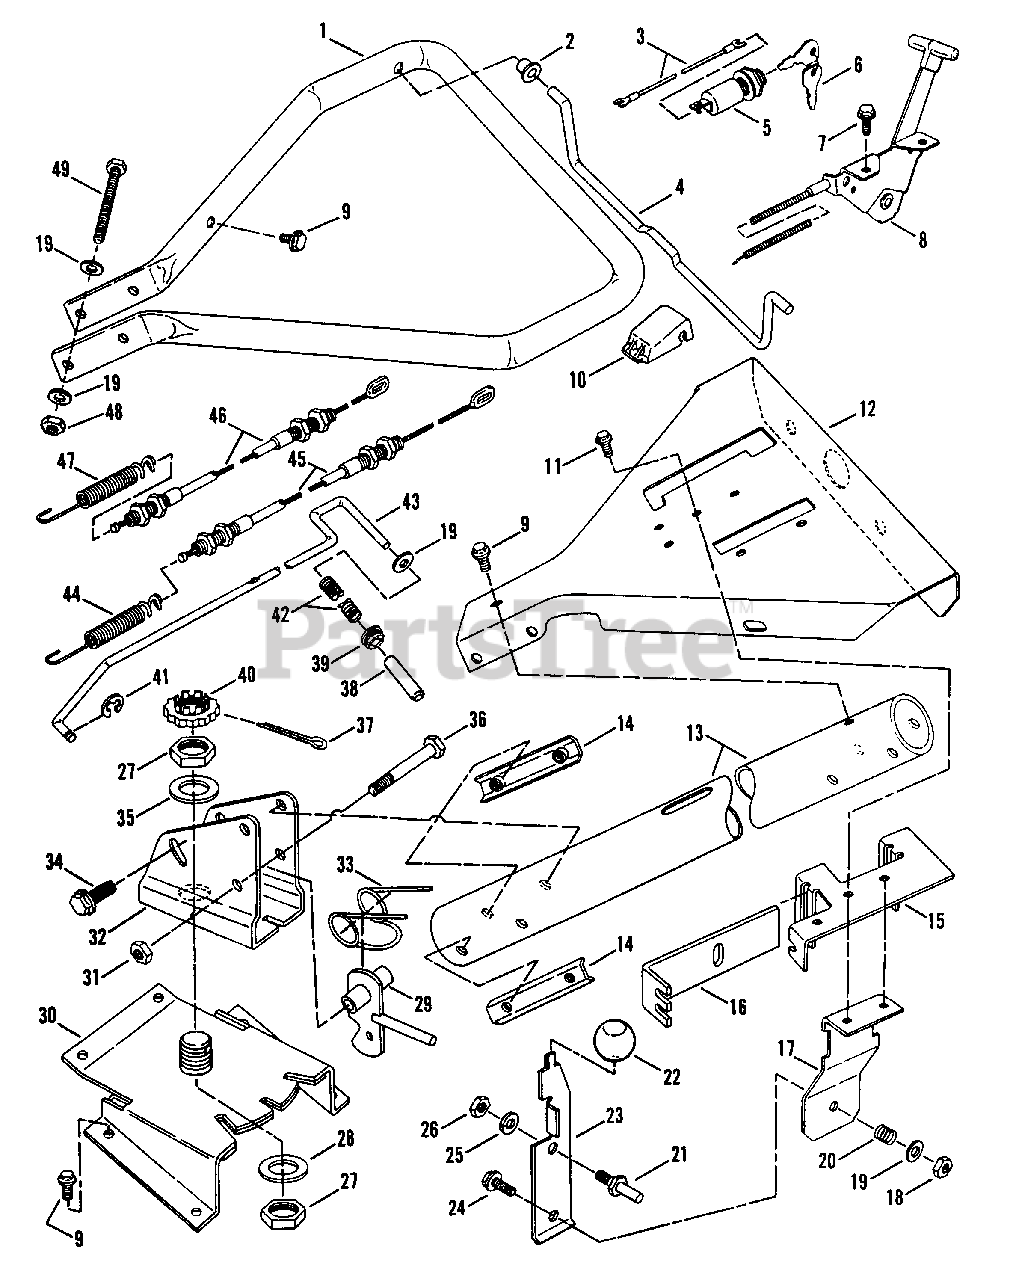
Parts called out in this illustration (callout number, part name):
1	BAR, Handle
2	BUSHING
3	(NLA) WIRE, Ground 40" (RT8 Manual Start)
4	(NLA) BAIL
5	SWITCH, Ignition (RT8 Manual Start)
6	KEY, Switch
7	SCREW, 1/4-20 x 3/8" Self-Tapping
8	CONTROL, Throttle (8HP)
8	CONTROL, Throttle (RT5X)
9	SCREW, 5/16-18 x 1/2" Self-Tapping
10	CLIP, Cable
11	SCREW, 1/4-20 x 1/2" Self-Tapping
12	PANEL (8HP)
12	PANEL (RT5X)
13	(NLA) TUBE, Handle Bar Support
14	(NLA) PLATE, Tap Nut
15	BRACKET, Cable
16	SLIDE
17	(NLA) BRACKET
18	NUT, 5/16-24 Hex Center-Lock
19	WASHER, 5/16 Flat
20	SPRING
21	STUD, Shift
22	KNOB, 1.62" DIA 3/8-16
23	HANDLE, Clutch
24	SCREW, 5/16-24 x 1 1/4" Hex Head Cap (Grade 2)
25	WASHER, 5/16 Split Lock
26	NUT, 5/16-18 Hex
27	NUT, 3/4-16 Hex Lock
28	WASHER, 3/4 Flat
29	(NLA) LATCH
30	BRACKET, Latch
31	NUT, 3/8-24 Hex Center-Lock
32	BRACKET, Handle
33	SPRING
34	BOLT, 3/8-16 x 3/4" Hex Flange Lock
35	WASHER, 13/16 Flat
36	SCREW, 3/8-24 x 2 1/2" Hex Head Cap
37	COTTER-PIN, 5/32 x 1 1/4"
38	GRIP, Handle Release (8HP)
39	BUSHING, 3/8" (8HP)
40	RETAINER, Nut Locking
41	E-RING 1/4 ID (8HP)
42	SPRING (8HP)
43	ROD, Handle Release (8HP)
44	SPRING, Traction Cable
45	CABLE, Traction Control
46	CABLE, Tine Control
47	SPRING, Tine Cable
48	NUT, 5/16-18 Hex Lock
49	SCREW, 5/16-18 x 3" Hex Head Cap
